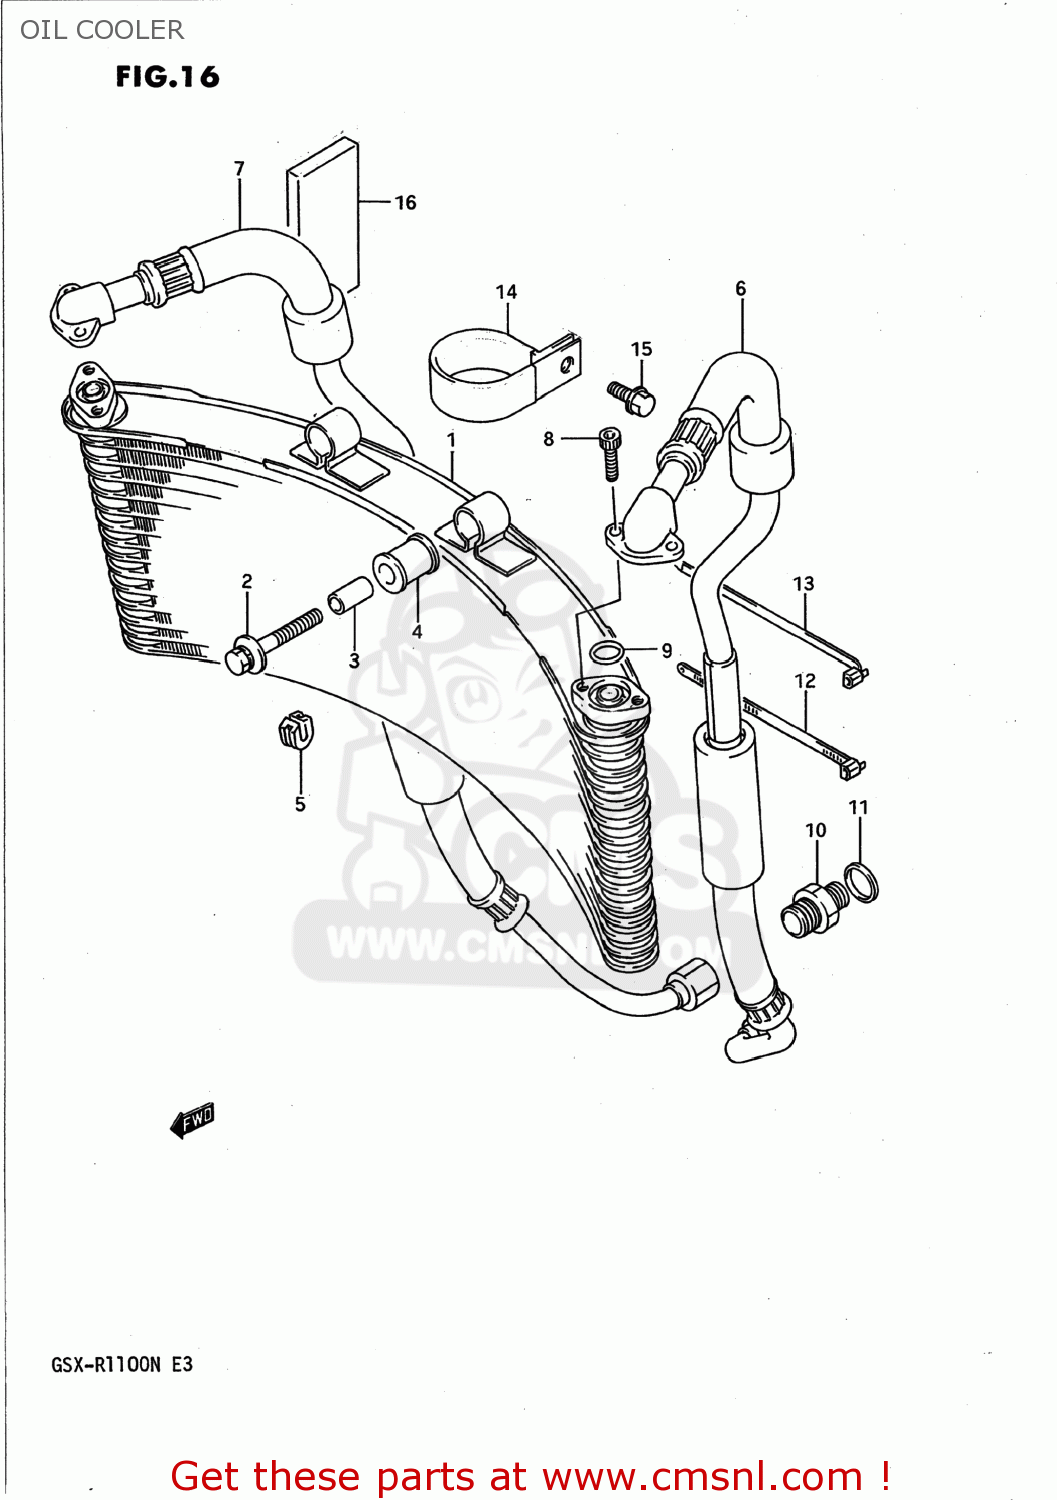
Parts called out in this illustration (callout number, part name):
1	COOLER ASSY,OIL
2	BOLT(8X40)
3	SPACER (8.8X12X24.5)
4	CUSHION,OIL COOLER NO.1
5	CUSHION,OIL COOLER NO.2
6	HOSE,OIL COOLER,L
7	HOSE,OIL COOLER,R
8	BOLT
9	O RING(D:2.4,ID:12.3)
10	BOLT UNION
11	GASKET(16X22X2) (NAS)
12	CLAMP
13	CLAMP(L:235)
14	CLAMP
15	BOLT
16	PROTECTOR
